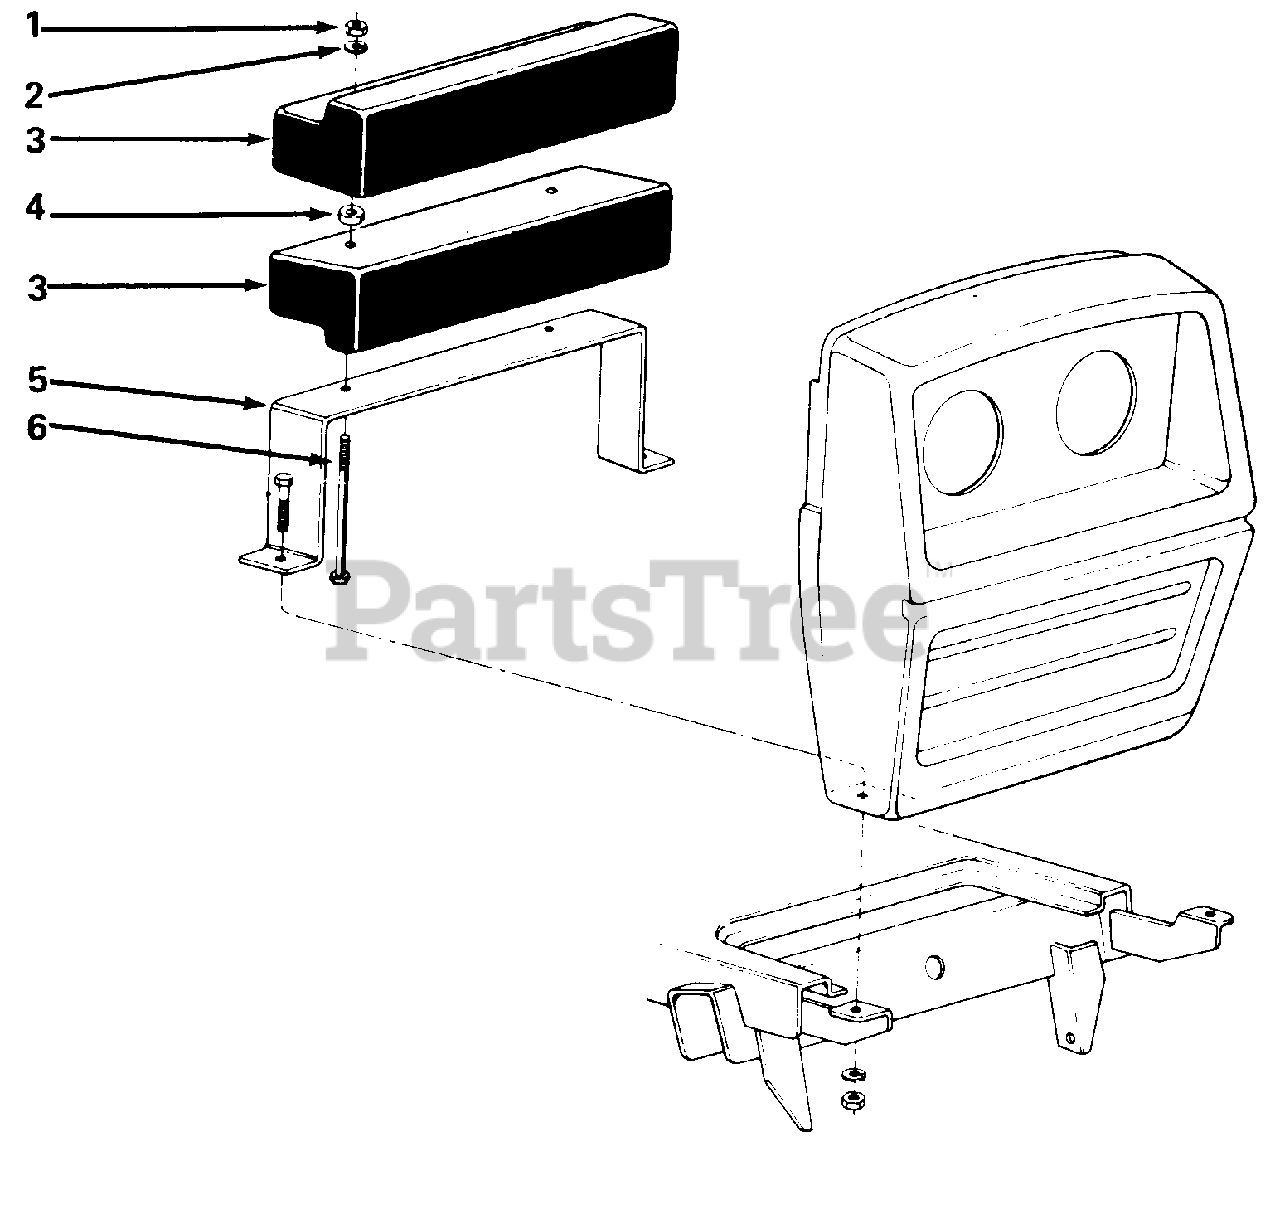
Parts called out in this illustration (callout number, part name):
1	Hex Nut 3/8-16 Thd.*
2	L.-Wash. 3/8 I.D.*
3	Weight - 35 Ib.
4	Spacer
5	Front Weight Bracket
6	Hex Bolt 3/8-16 x 6.5" Lg.
